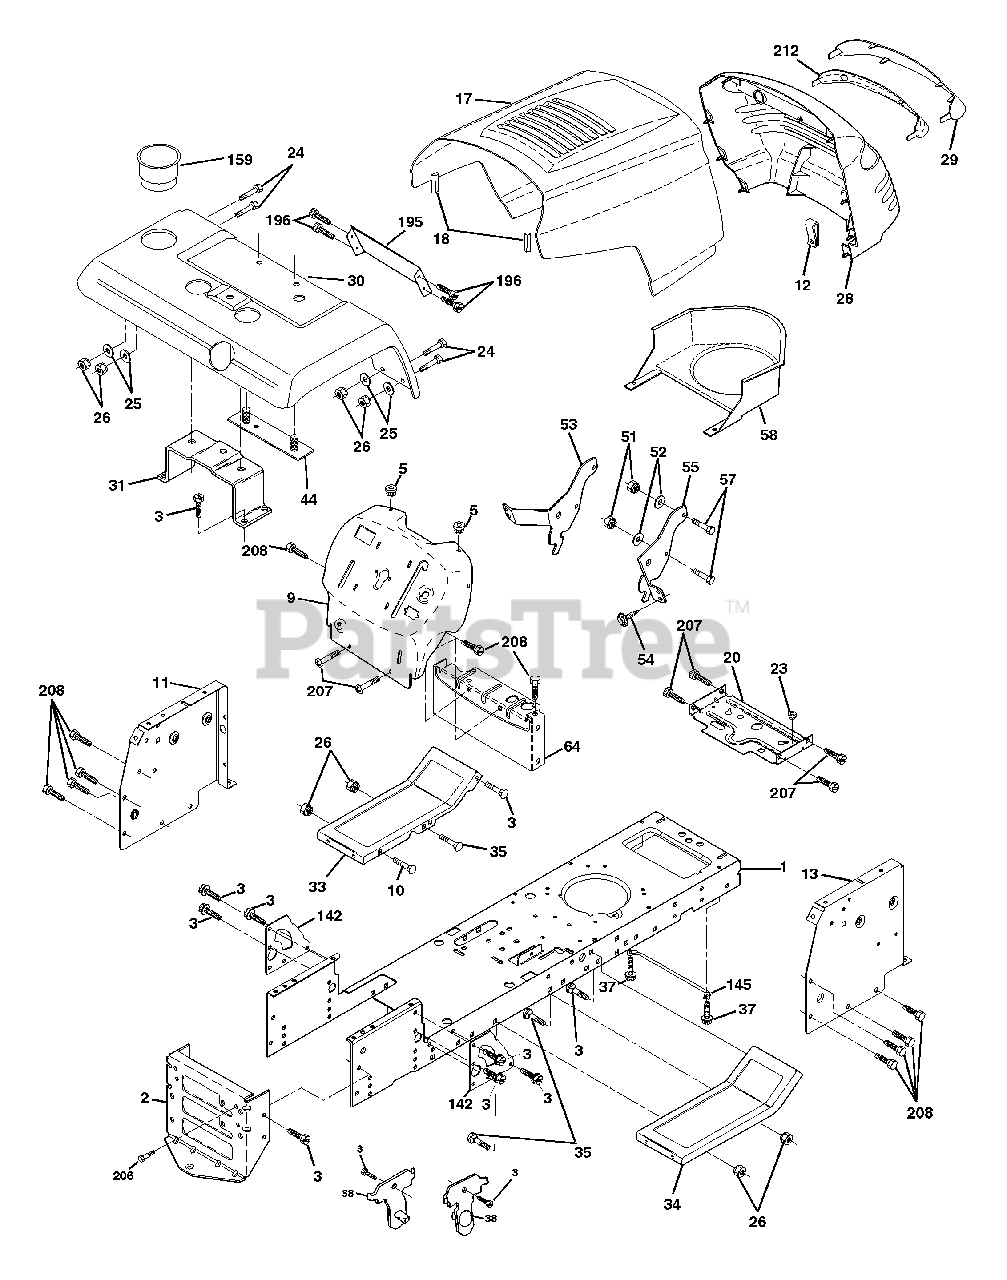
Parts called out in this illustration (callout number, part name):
1	Chassis
2	Drawbar
3	Screw 3/8-16x3/4
5	Bumper Hood/Dash
10	Bolt Carriage 3/8-16 x 1
11	Panel Dash Lh
12	Clip Tinnerman
13	Panel Dash Rh
17	Hood LT/PL
18	Bumper Hood
20	Plate Mtg Battery Fuel Tank Fr
23	Bushing
24	Bolt Fin Hex 3/8-16 x 1 Gr 5
25	Washer 13/32 X 13/16 X 12 Ga
26	Nut Lock Hex W/Ins 3/8-16 Unc
28	Grille LT/PL
29	Lens LT/PL
30	Fender Pnt YTST
31	Bracket Fender
33	Footrest Pnt Lh
34	Footrest Pnt Rh
35	Bolt Rdhd Sht Sqnk 3/8-16 x 3/4
37	Screw Thdrol 6/16-18 x 1/2 TYT
38	Bracket, Asm. Pivot Mower Rear
44	Strap Asm Fender
51	Nut Lock Hex W/Ins 1/4-20
52	Washer 9/32 x 7/8 x 16 Ga.
53	Bracjet Grukke Lh
54	Screw Hex Wshd 8-18 x 7/8
55	Bracket Grille Rh
57	Bolt Hex 1/4-20 x 3/4
58	Duct Air
64	Dash Lower STLT
142	Plate Reinforcement STLT
145	Rod Pivot Chassis/Hood
159	Cupholder
195	Panel Pnt Fender YT/GT
196	Screw Tap Tite 1/4-20 x 1/2
206	Bolt Shoulder 5/16-18
207	Screw Thdrol 5/16-18 x 1/2
208	Screw Thdrol 3/8-16 x 1/2
212	Insert Lens Reflect P/L LT SVC
